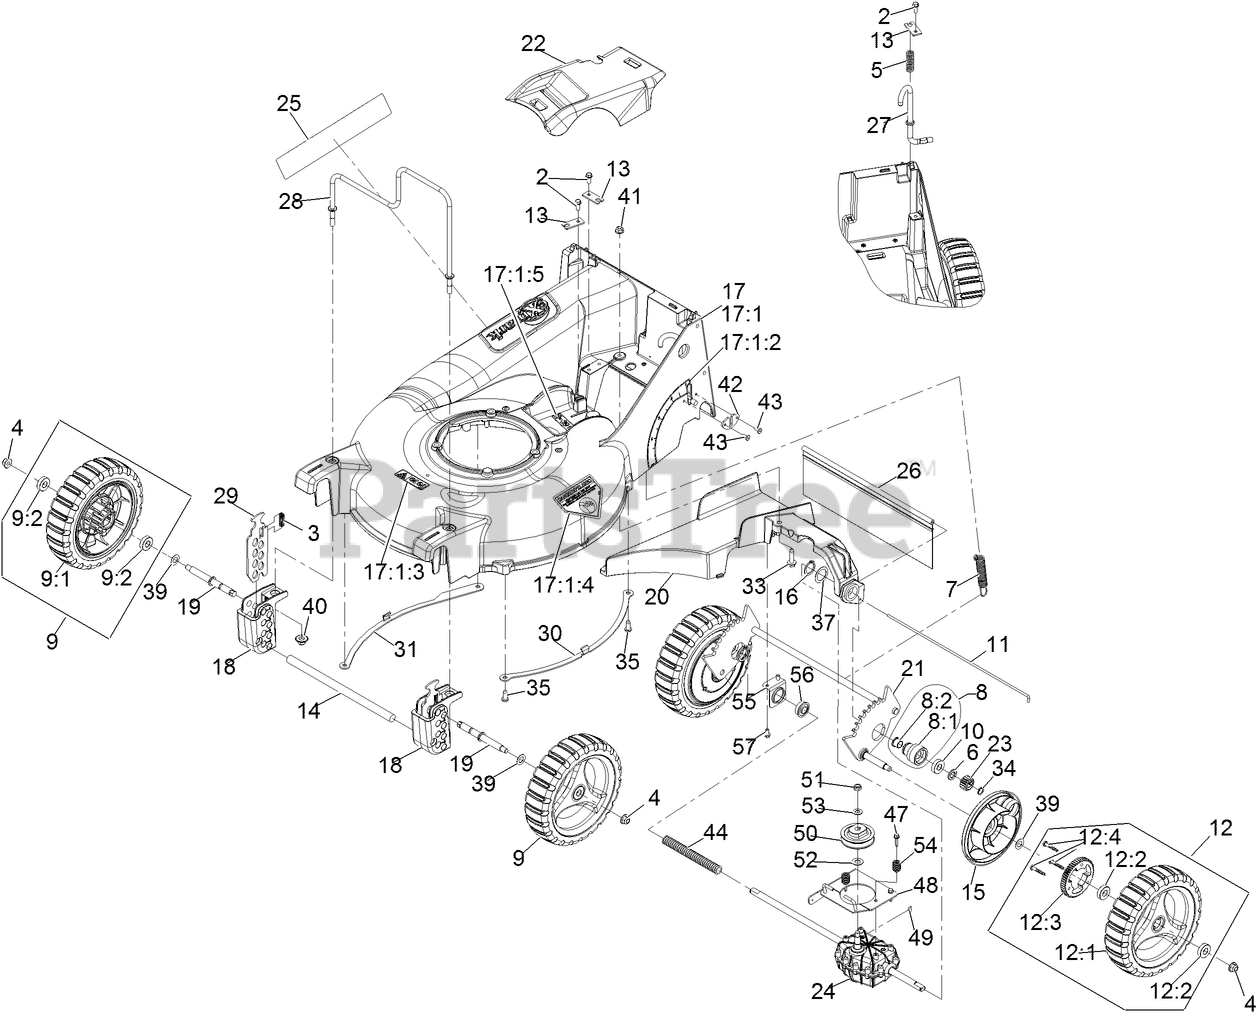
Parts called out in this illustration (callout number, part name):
2	SCREW-HWH
3	SPRING-COMPRESSION
4	NUT-HF, NI
5	SPRING-COMPRESSION
6	SPACER-BUSHING
7	SPRING-EXTENSION
8	HOUSING ASM
8:1	HOUSING-BEARING
8:2	BEARING-FLANGE
9	WHEEL ASM, 9" W/BEARINGS
9:1	WHEEL ASM, 9
9:2	BEARING-BALL
10	BEARING-BALL
11	ROD,SHIELD
12	WHEEL ASM, 9 W/GEAR
12:1	WHEEL ASM, 9
12:2	BEARING-BALL
12:3	GEAR-WHEEL, 52T
12:4	STUD-DRIVE
13	BRACKET,MOUNT
14	ROD,BUMPER
15	COVER,GEAR
16	RING-RETAINING
17	DECK-ASM, COM21 BOXED
17:1	Deck W/Decals
17:1:2	DECAL-HEIGHT OF CUT
17:1:3	DECAL-WARNING, BLADE
17:1:4	DECAL-DANGER
17:1:5	DECAL-DANGER
18	BLOCK,FRONT QUADRANT
19	AXLE-WHEEL
20	Bracket-Transmission And Chute
21	WLD,REAR AXLE P21
22	COVER,BELT
23	GEAR-PINION, 15T
24	TRANSMISSION-HD, 4.5/1
25	DECAL-COMM 21 X-SERIES
26	SHIELD-TRAILING P21
27	ROD-HEIGHT ADJ P21
28	GUARD,ENGINE
29	PLATE, FRONT HEIGHT
33	SCREW-HWHTF
34	RING-RETAINING
35	SCREW-BHTF
39	WASHER-PLAIN
40	Nut-Nyloc 3/8-16 Flg
41	NUT-HF, NI
42	PLATE,WEAR
43	RIVET-BLIND
44	COVER-SHAFT-DRIVE
47	SCREW-SPECIAL
48	TRANSMISSION PLATE ASM
49	KEY-WOODRUFF
51	NUT-HEX
52	WASHER-THRUST
53	WASHER-FLAT
54	SPRING,COMPRESSION
55	MOUNT-BEARING
56	BEARING-BALL
57	SCREW-HWH
